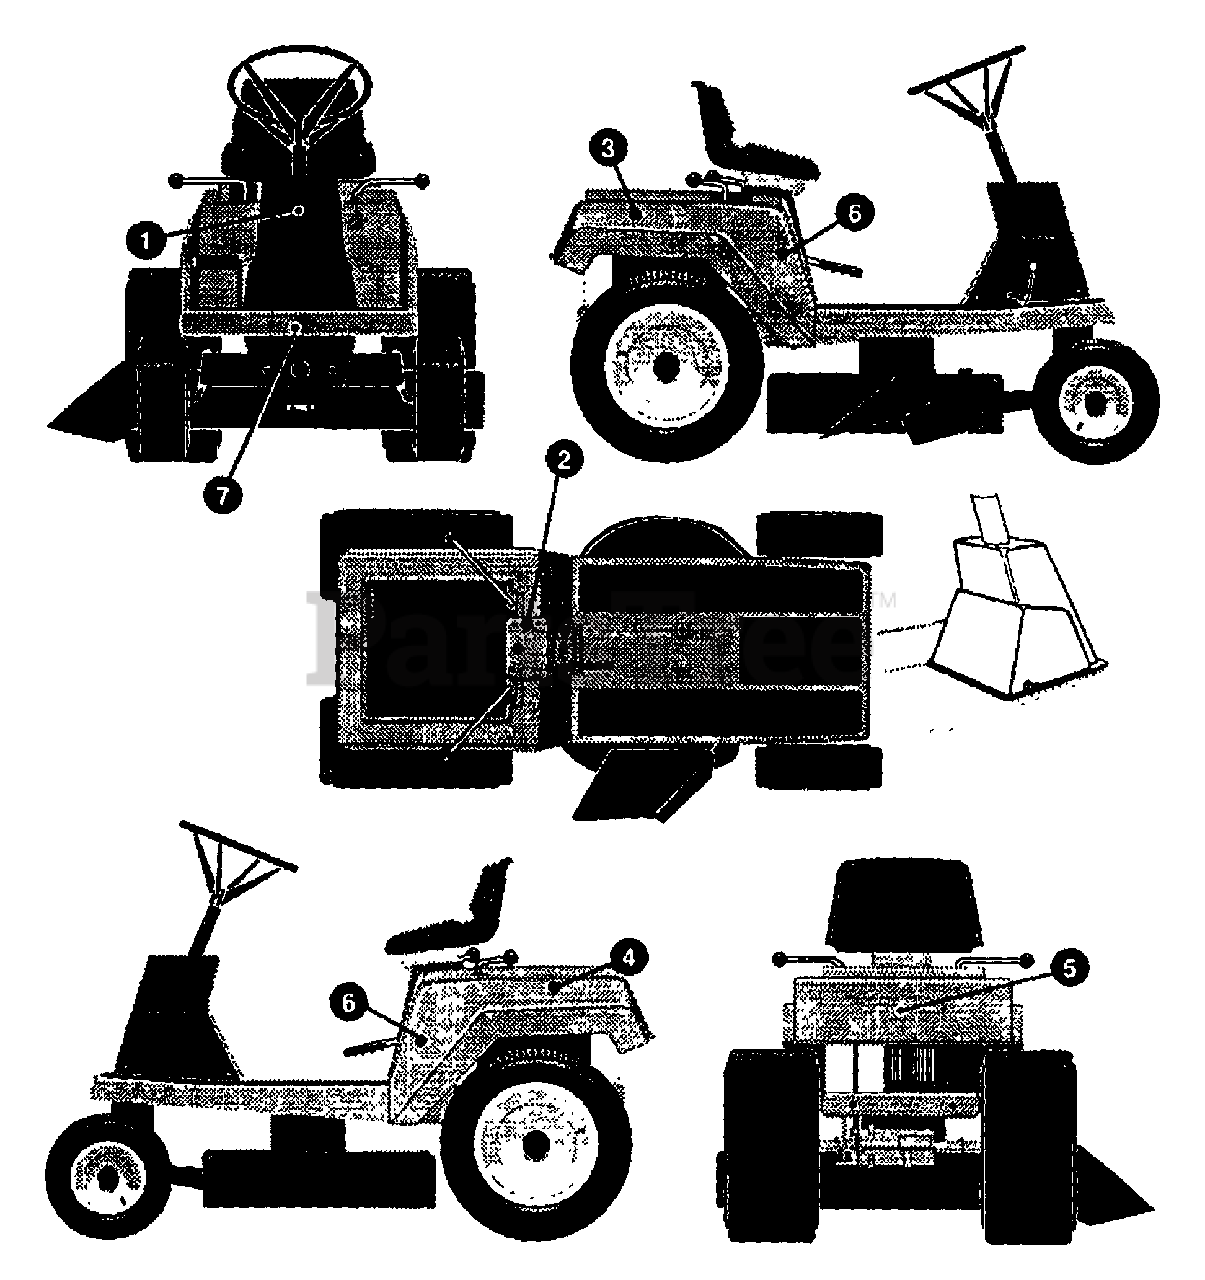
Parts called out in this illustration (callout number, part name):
1	DECAL FENDER REAR, HOOD HUSG
2	REFERENCE ONLY
3	DECAL, FENDER RH RER
4	DECAL, FENDER LH RER
5	DECAL, FENDER REAR, HOOD HUSQ.
6	DECAL FRAME FRONT RER
